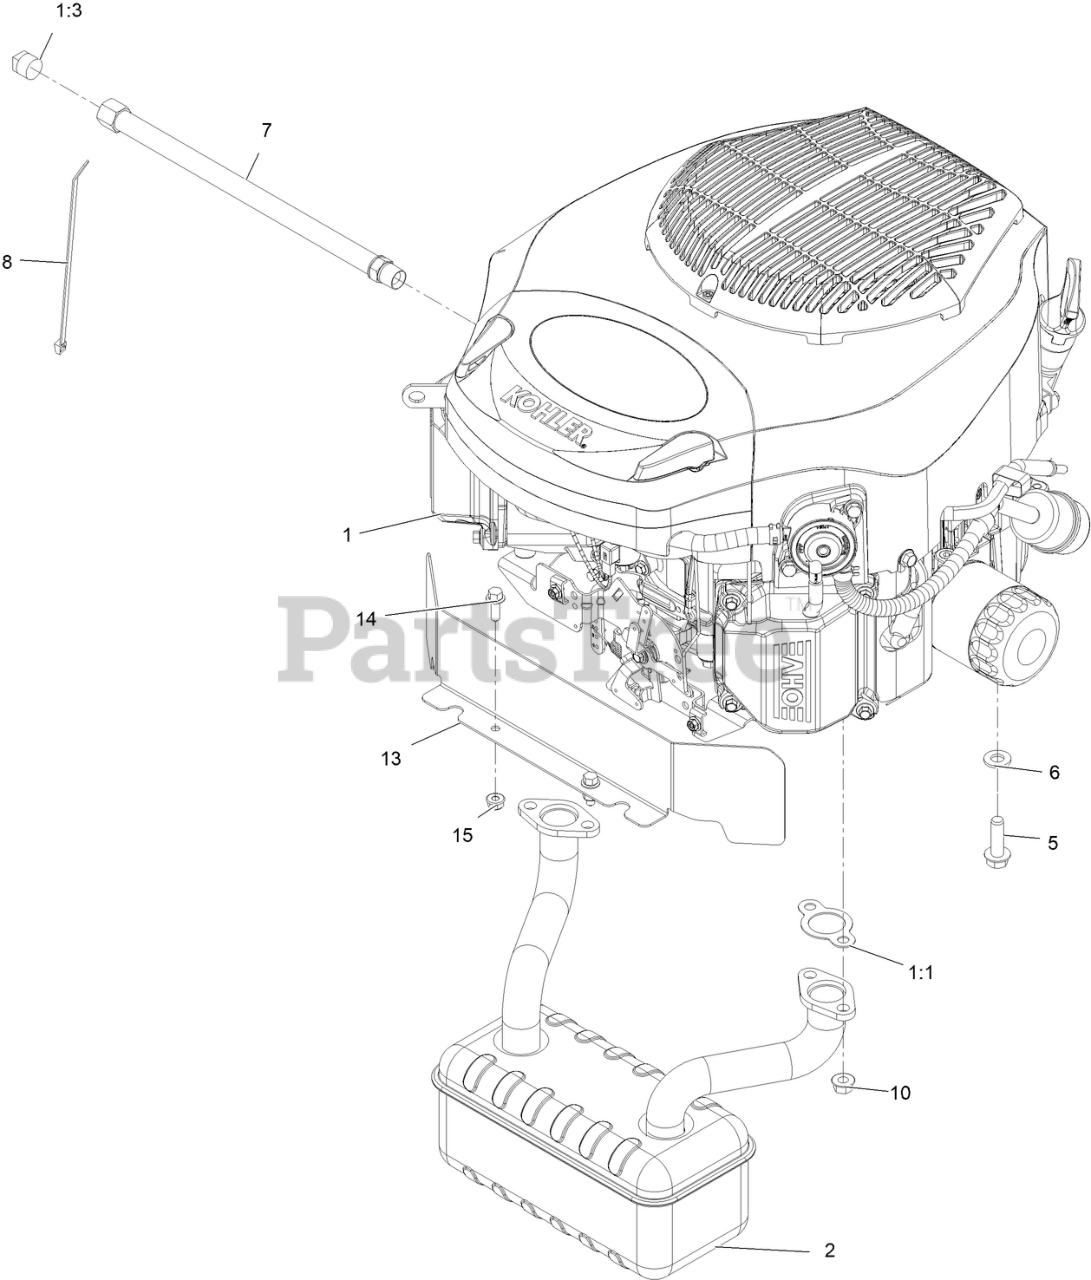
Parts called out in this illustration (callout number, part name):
2	Muffler
5	SCREW-THD
6	WASHER-FLAT
7	HOSE-DRAIN, OIL
8	TIE-CABLE
13	SHIELD-HEAT
14	Screw-HHF
15	SCREW-SHOULDER
